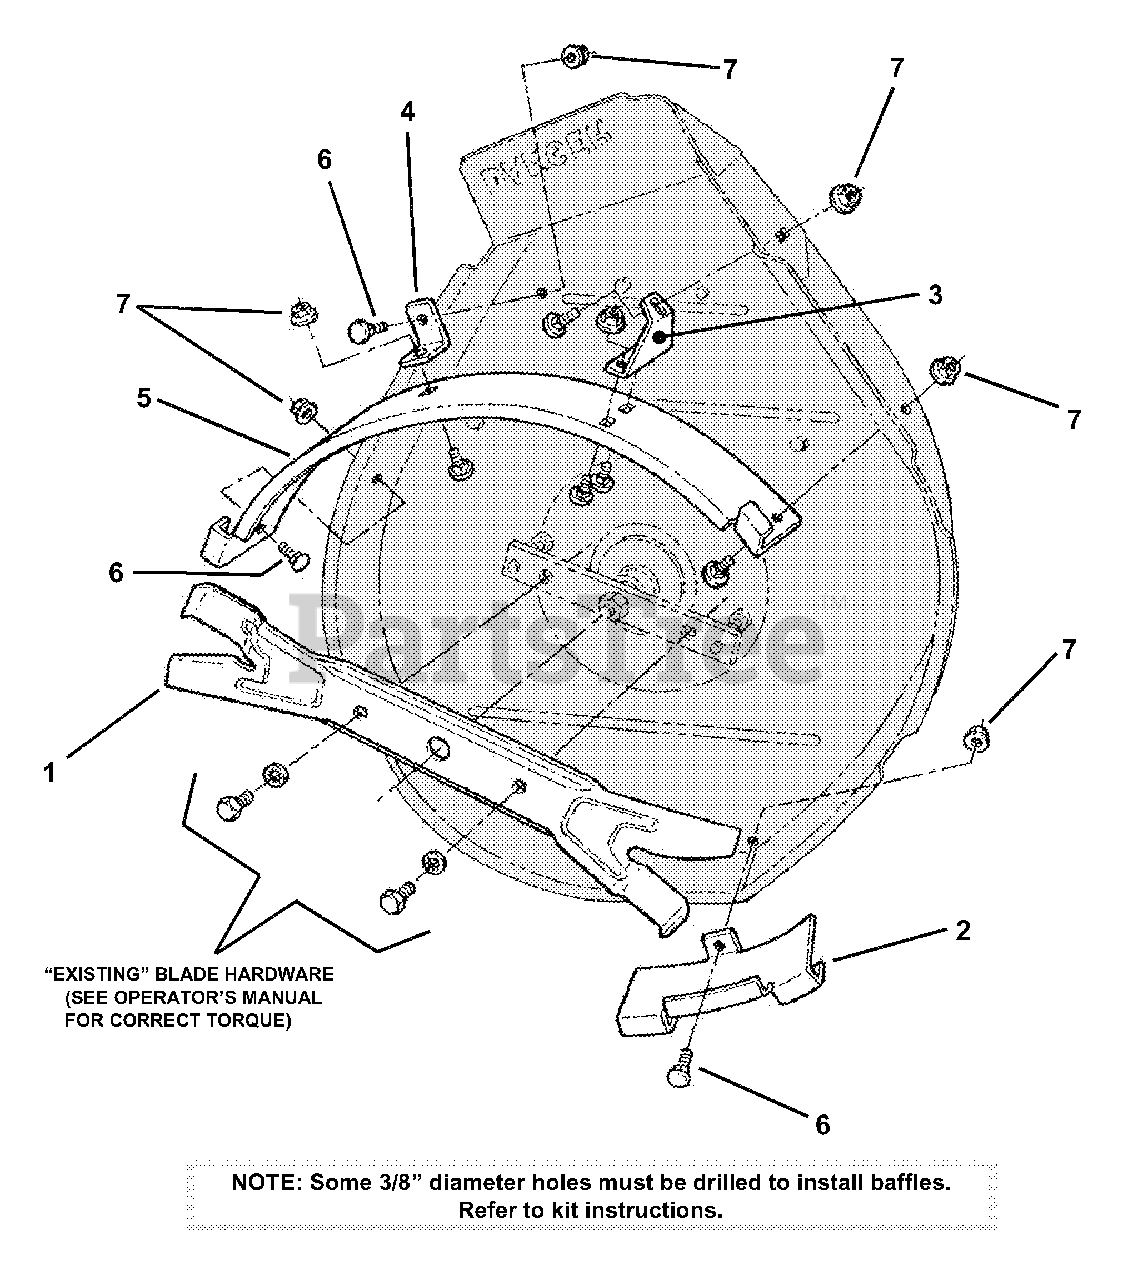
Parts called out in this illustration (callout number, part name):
1	BLADE, 30" Ninja (Quad Edge)
2	BAFFLE, 30" Deck
3	ANGLE, Brace
4	ANGLE, Brace
5	BAFFLE, 30" Deck
6	BOLT, 5/16-18 x 5/8" Short Neck Carriage, Grade 5
7	NUT, 5/16-18 Hex Flange Lock, Grade 5
